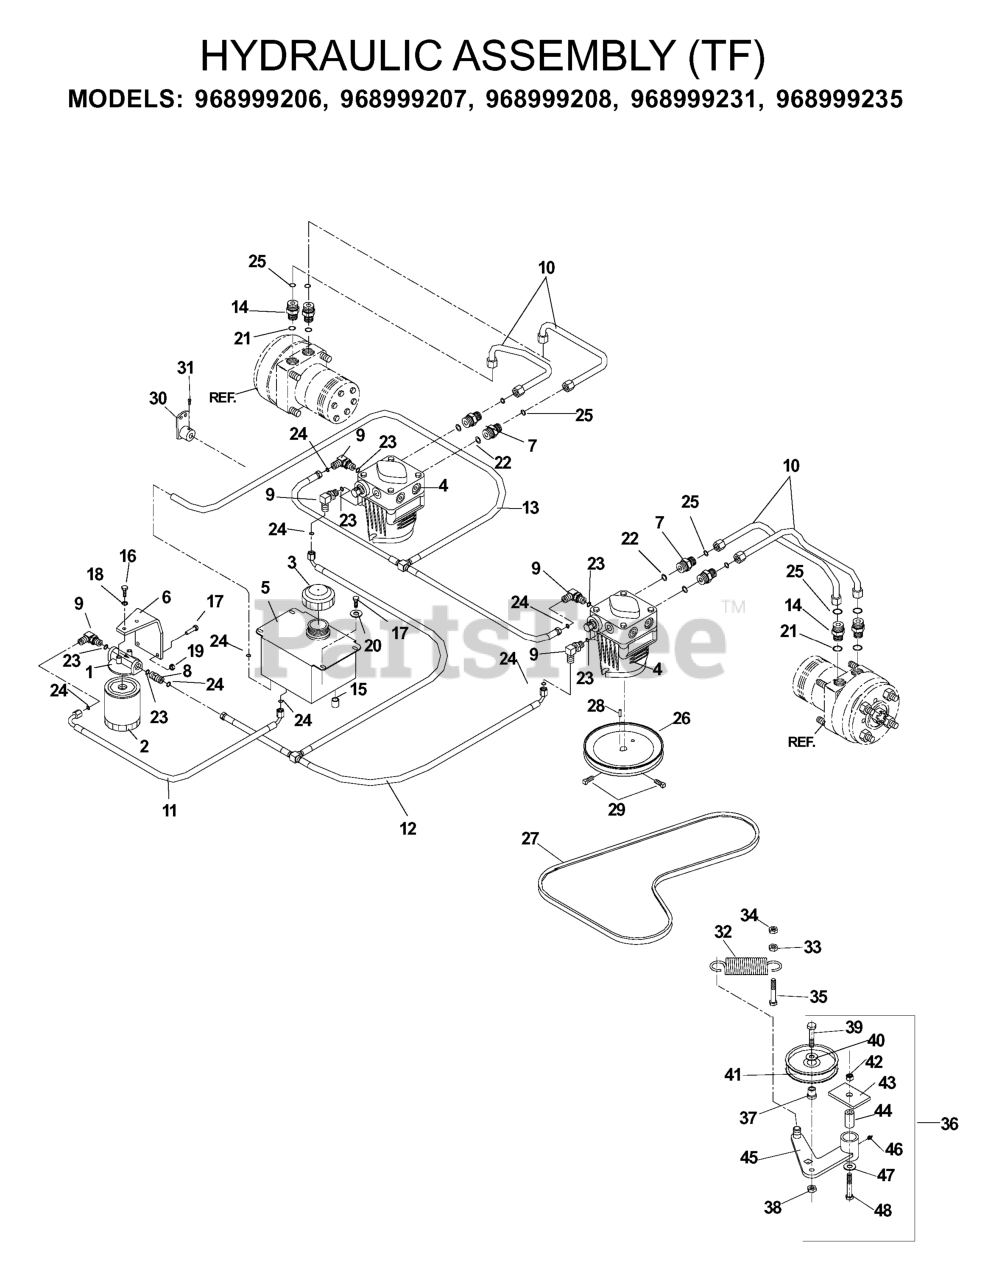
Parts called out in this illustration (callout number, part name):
1	FILTER HEAD
2	HYDRAULIC OIL FILTER
3	HYDRAULIC CAP
4	HG_PUMP
6	OIL FILTER BRKT
7	FITTING, STRAIGHT F6400-8-8-0
8	STRAIGHT FITG
9	ELBOW, F6801-6-6-0 90 DEGREE
10	HYDRAULIC HOSE
12	TEE ASSEMBLY
13	TEE ASSEMBLY
15	NUT 9/16-18 JIC CAP
16	HCS 1/4C X 5/8
17	HCS 1/4C X 3/4 HCS
18	LOCKWASHER 1/4"
19	NUT.1/4-20.HEX.NYLOC.ZD
20	WASHER 1/4 FLAT
27	PUMP BELT
28	KEY 5 MM SQ X 25 MM
29	SCREW 5/16C X 5/8 SQ HEAD
30	PUMP LEVER
31	5/16C X 5/8 "V" POINT
33	NUT 3/8C WHIZ
34	NUT 3/8-16 NYLOC
35	HCS 3/8C X 2
36	TORSION SPRING
37	BUSHING, IDLER FLANGE
38	NUT 3/8C CENTERBLOCK
39	HCS 3/8-16 X 1 3/4 GR5
40	WASHER 3/8 FLAT
41	IDLER PULLEY
42	NUT 1/2-13 HEX NYLOC ZD
44	PIVOT BUSHING
45	IDLER ARM WLDT
46	ZERK
47	WASHER 1/2 FLAT
48	HCS 1/2C X 3 1/4
